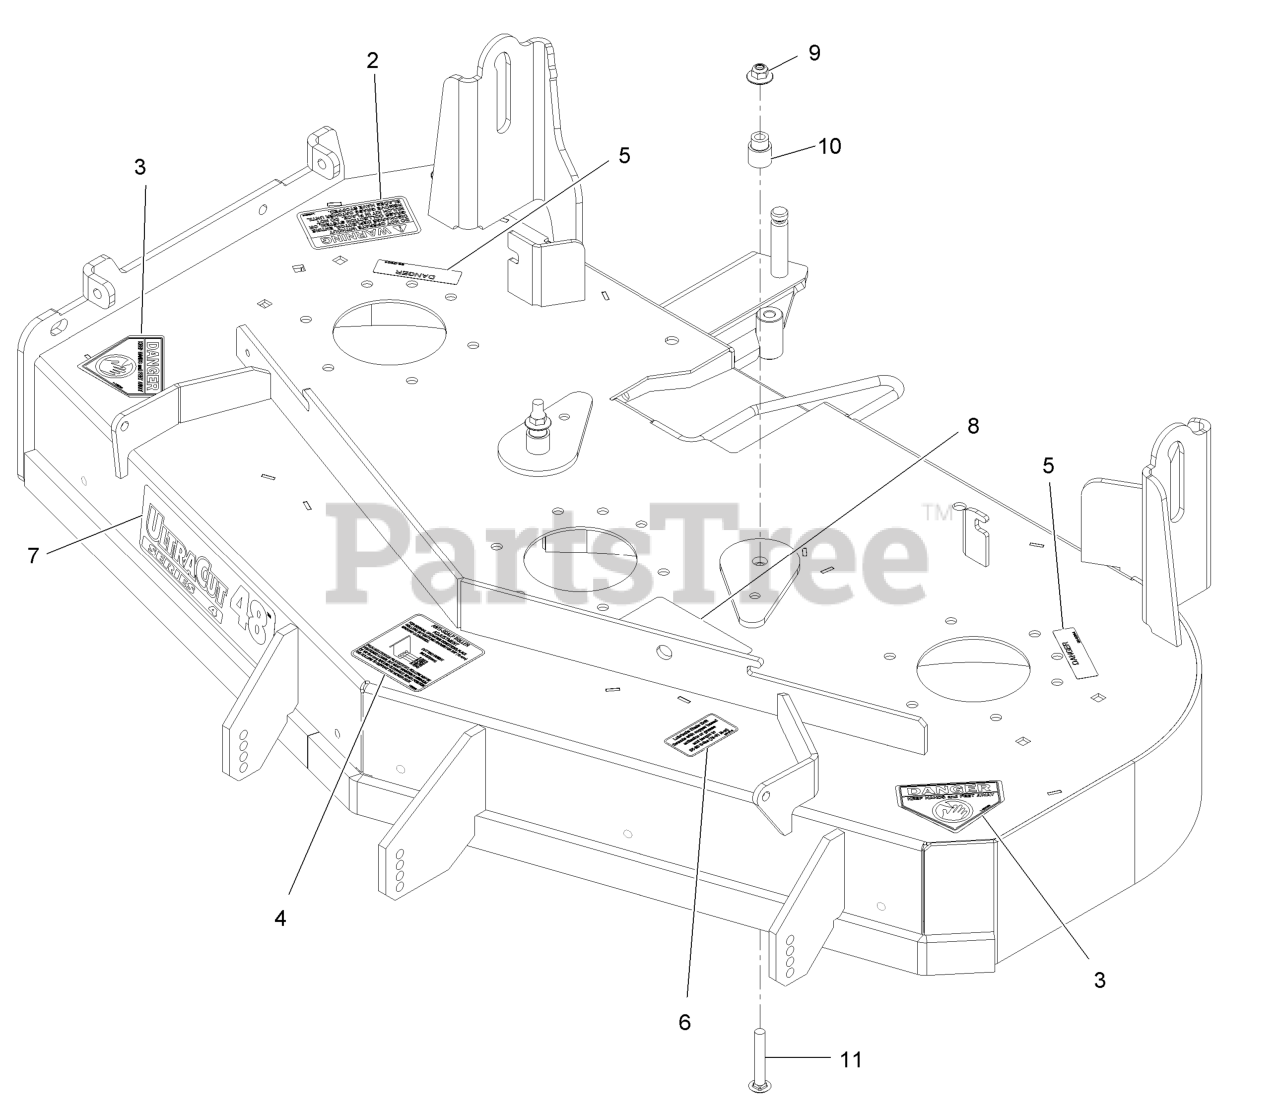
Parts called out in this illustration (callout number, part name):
2	DECAL-WARNING, DISCHARGE
3	DECAL-DANGER
4	DECAL,ANTISCALP
5	DECAL-COVER, MISSING
6	DECAL,BOLT TORQUE
7	DECAL,ULTRACUT 48 SERIES
8	DECAL-BELT ROUTING
9	Nut-Nyloc 3/8-16 Flg
10	BUSHING-IDLER
11	SCREW-CARR
